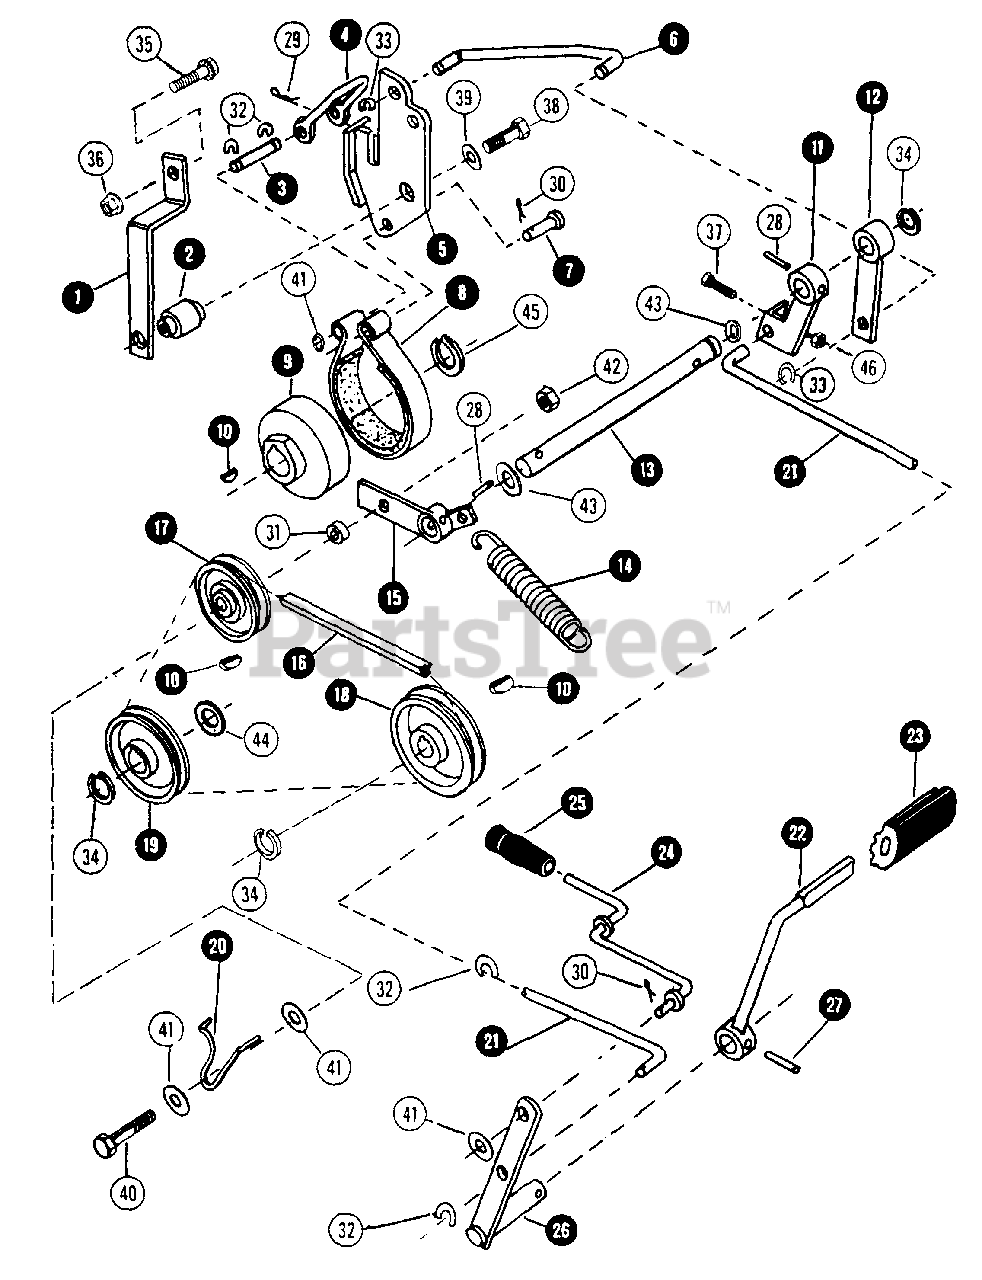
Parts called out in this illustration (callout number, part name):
1	BRACKET, BRAKE PIVOT SUPPORT
2	PIVOT, BRAKE LEVER
3	PIN, LINK TO BRAKE BAND
4	LINK, BRAKE BAND TO LEVER
5	LEVER, BRAKE
6	ROD, BRAKE ACTUATOR
7	PIN, BAND TO LEVER
8	BAND, BRAKE (ASSEMBLY)
9	DRUM, BRAKE
10	KEY, PULLEY - 3/16 x 3/4 WOODRUFF
11	ARM, CLUTCH & BRAKE ACTUATOR
12	ARM, BRAKE ACTUATOR
13	CROSS-SHAFT, CLUTCH & BRAKE
14	SPRING, CLUTCH RETURN
15	ARM ASSEMBLY
16	V-BELT, TRANSAXLE DRIVE
17	PULLEY, DRIVE
18	PULLEY, DRIVE
19	PULLEY, DRIVE
20	GUIDE, BELT
21	ROD, CLUTCH & BRAKE ACTUATOR
22	PEDAL, CLUTCH & BRAKE
23	PAD, PEDAL
24	LEVER, PARKING BRAKE
25	GRIP, Handle
26	ARM, PEDAL PIVOT
27	PIN, PEDAL
28	PIN, ARM TO SHAFT GROOVE
29	PIN, BRAKE BAND RETAINING HAIR
30	COTTER-PIN, 3/32 x 3/4
31	SPACER, IDLER PULLEY TO CLUTCH ARM
32	RING, ACTUATOR
33	RING, ROD RETAINING
34	RING, PULLEY RETAINING
35	BOLT, 3/8C x 7/8 FLANGE LOCK
36	NUT, 3/8C x 1-3/4 FLANGE
37	CAPSCREW, 5/16C x 1-1/4 HEX HEAD
38	BOLT, 3/8C x 1-3/4 FLANGE
39	WASHER, 3/8 FLAT - SPECIAL
40	CAPSCREW, 3/8C x 2-1/4 HEX HEAD
41	WASHER, 3/8" Flat
42	NUT, 3/8C HEX
43	WASHER, SHIM (25/32 x 1-5/16 x 1/32")
44	WASHER, THRUST (49/64 x 1-1/2 x 1/16")
45	RING, RETAINING - DRUM TO TRANSAXLE
46	NUT, 5/16C MACHINE SCREW
